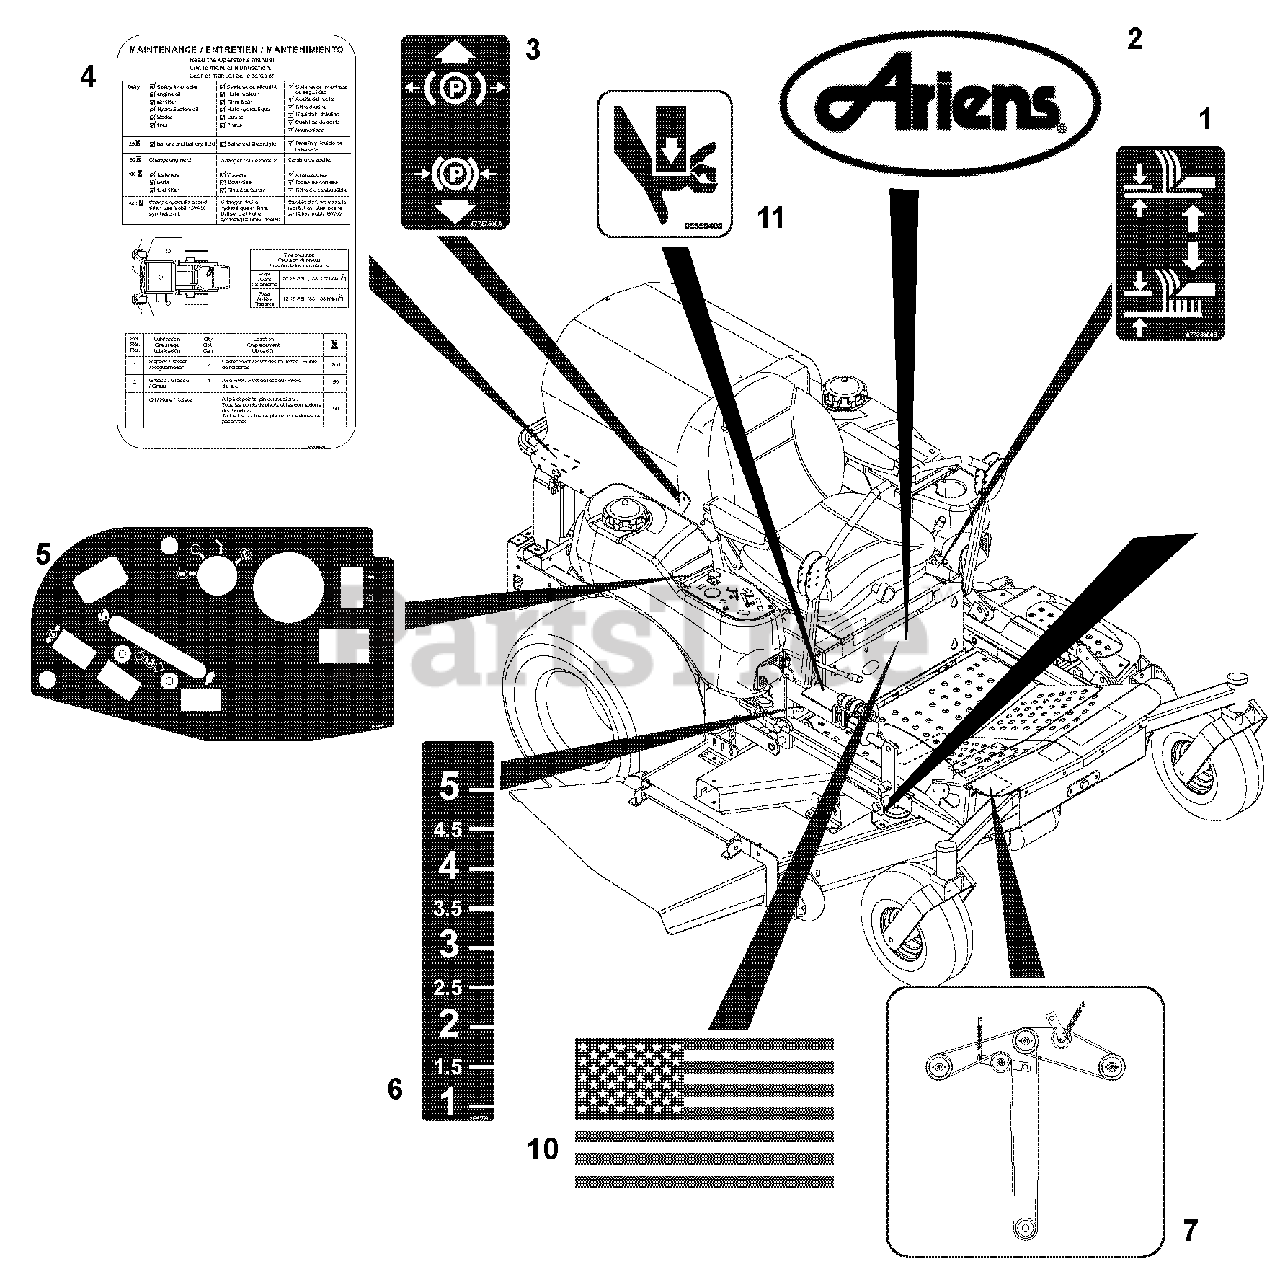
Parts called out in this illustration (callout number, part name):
1	Decal, Lift Lever
2	Decal, Ariens
3	Decal, Parking Brake Lever
4	Decal, Service Instructions
5	Decal, Control Panel
6	Decal, Height of Cut
7	Decal, Belt Diagram
8	Decal, PM-260Z
9	Decal, 60
10	Decal, American Flag
11	Decal, Pinch Point
